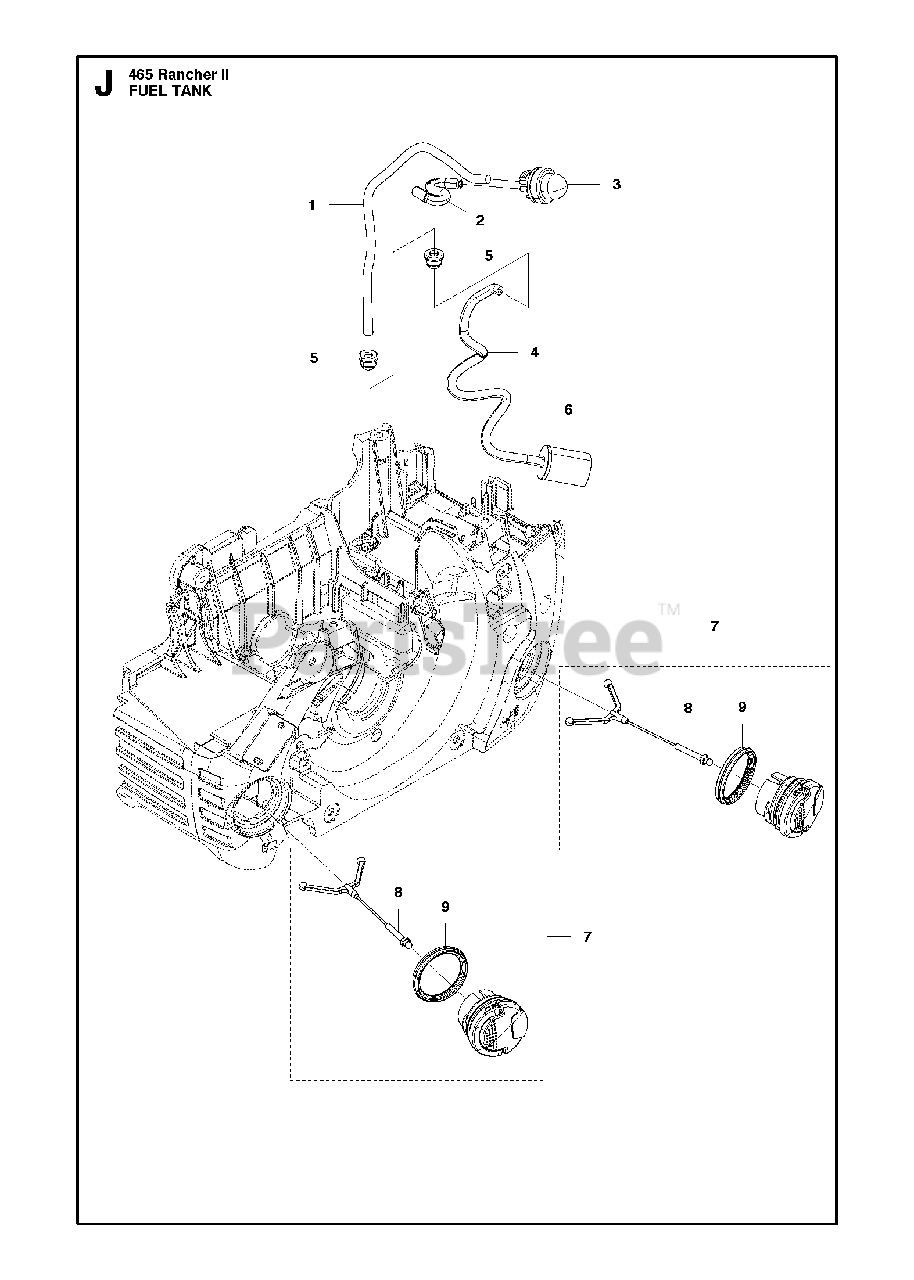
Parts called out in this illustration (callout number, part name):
1	FUEL HOSE
2	FUEL HOSE
3	AIR PURGE BUBBLE
4	FUEL HOSE SPIRAL 300
5	FUEL TANK BUSHING
6	FUEL FILTER
7	TANK CAP ASSY
8	TANK LOCK
9	SEALING
